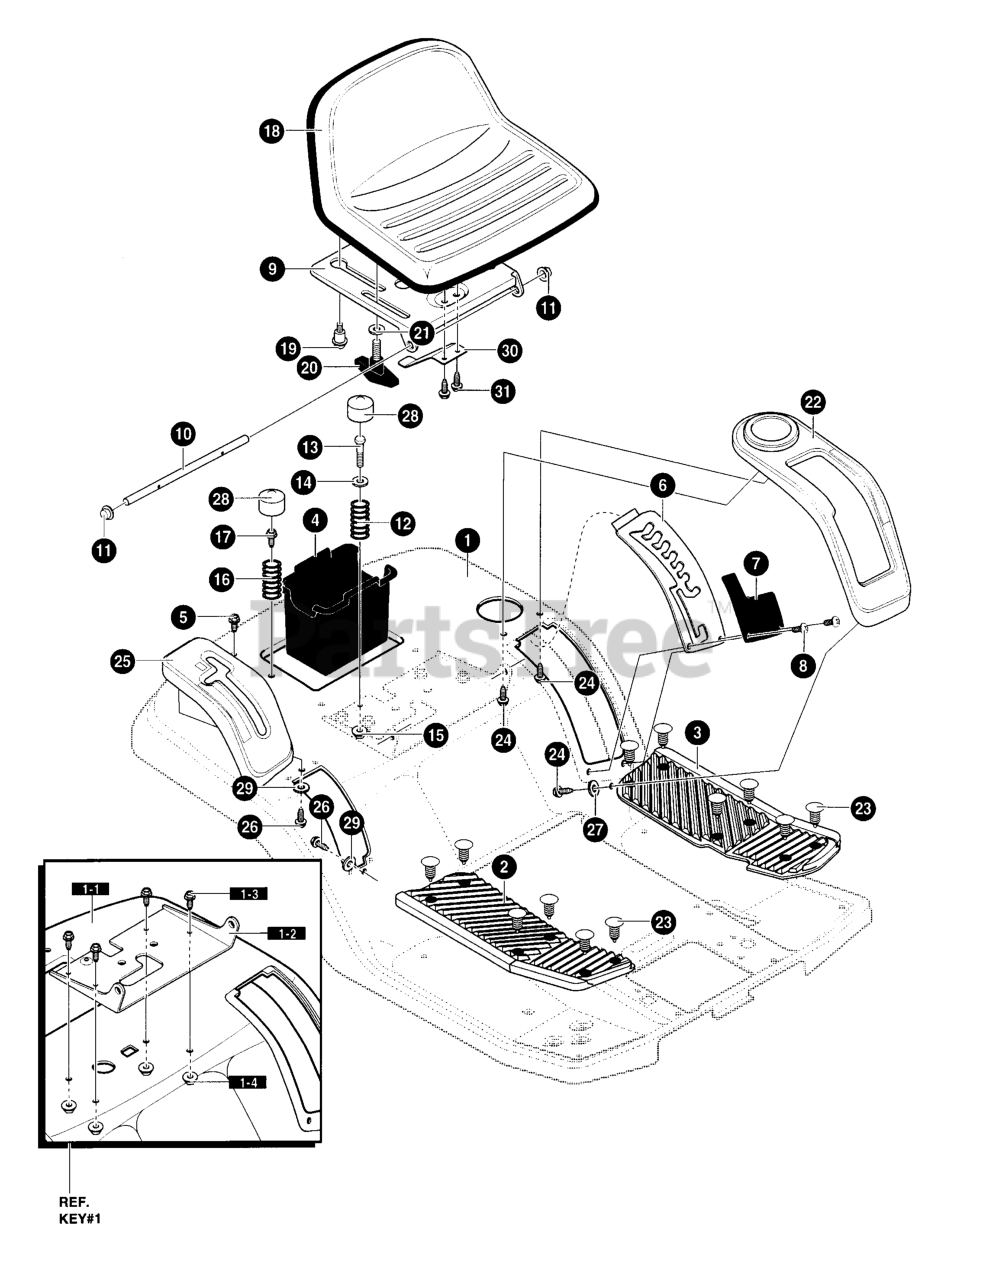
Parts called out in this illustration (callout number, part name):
1	LARGE SEAT DECK
1-1	SEAT DECK, LARGE
1-2	BRACKET, PIVOT SEAT
1-3	SCREW, 5/16-18 x 0.75
1-4	NUT, 5/16- 18
2	FOOT REST PAD RH
3	FOOT REST PAD LH
4	CONTAINER, BATTERY
5	SCREW 1/4-20X.63
6	PLATE, LIFT DETENT
7	COVER, LIFT DETENT
9	SUPPORT, SEAT
10	HINGE SEAT PIVOT
11	NUT, PUSH CAP
12	SPRING, COMPRESS
13	BOLT, SHOULDER 1/4-20
14	WASHER CUP
15	NUT, 1/4-20
16	SPRING, COMPRESS
17	SCREW 5/16- 18X.75
19	BOLT, SHOULDER 5/16- 18
20	BOLT, WING 5/16- 18X.50
21	Washer
22	COVER, DETENT PLATE
23	FASTENER, RATCHET
24	SCREW, 1/4- 15X.44/.53
25	COVER, HAND/FOOT, HYDRO
26	SCREW, 1/4- 15X.44/.53
27	FLATWASHER
28	CAP
29	WASHER, FLAT
30	SPRING, LEAF
31	SCREW, 1/4-20X.50
